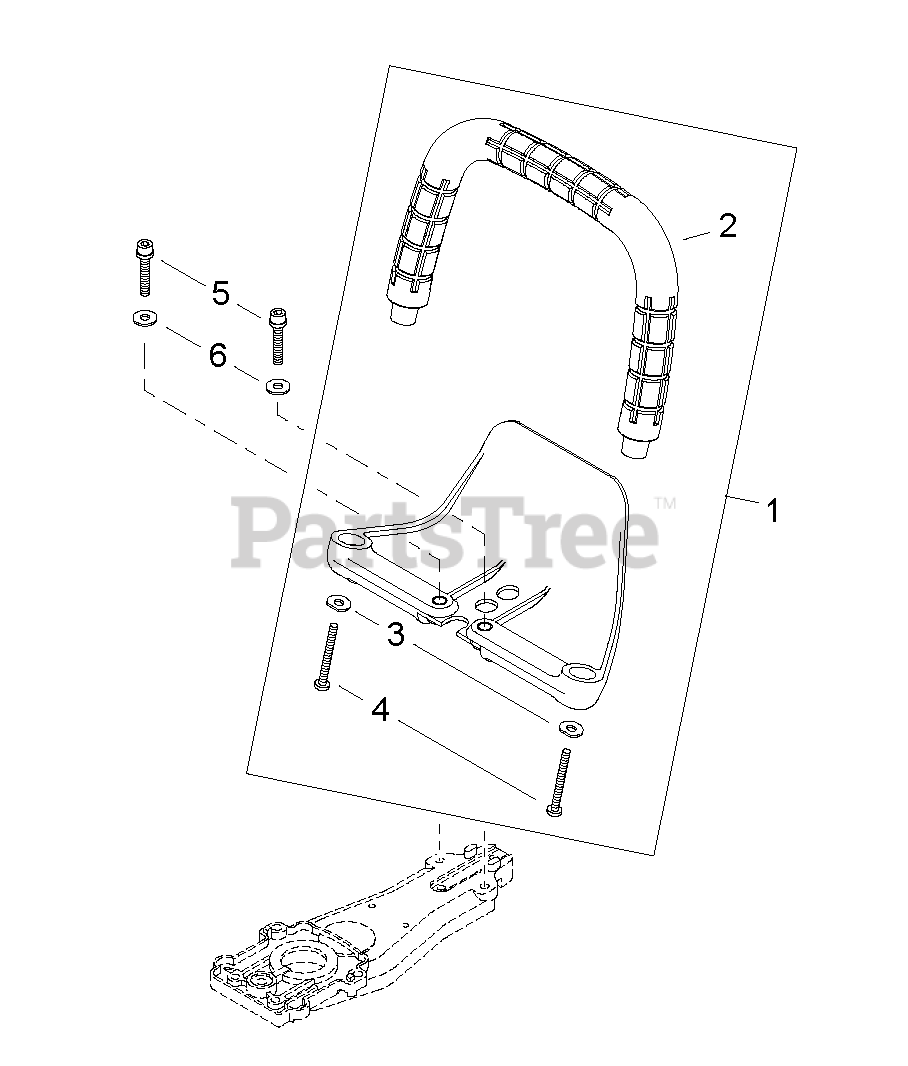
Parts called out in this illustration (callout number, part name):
1	HANDLE ASSY, FRONT
2	HANDLE, FRONT
4	BOLT, TAPPING 5
5	BOLT M6×35
6	WASHER Ø16ר6.5×1.6 MM
